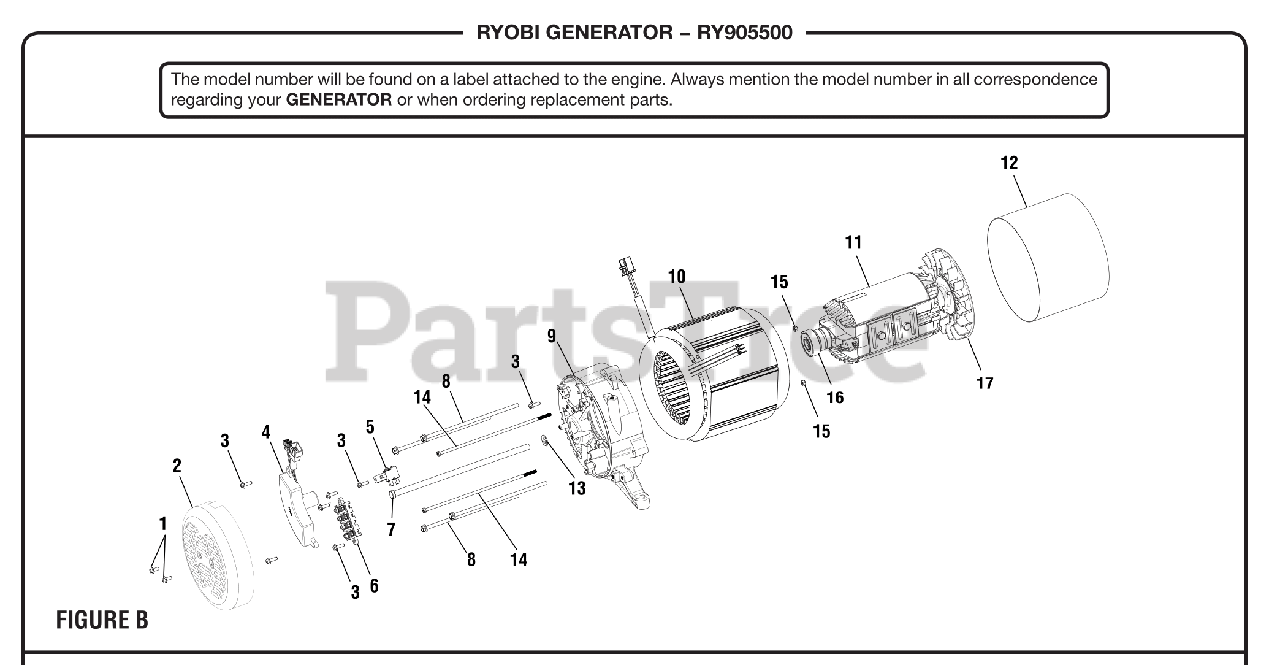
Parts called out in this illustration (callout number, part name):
1	Bolt (M5 x 12 mm, Hex Flange Hd.)
2	Brush Cover
3	Bolt (M5 x 16 mm, Hex Flange Hd.)
4	Automatic Voltage Regulator
5	Brush Assembly
6	Terminal Block
7	Rotor Bolt (M8 x 220 mm)
8	Stator Bolt (M6 x 180 mm)
9	Bearing Housing
10	Stator Assembly
11	Rotor Assembly
13	Rotor Washer
14	Bolt (M6 x 200 mm)
